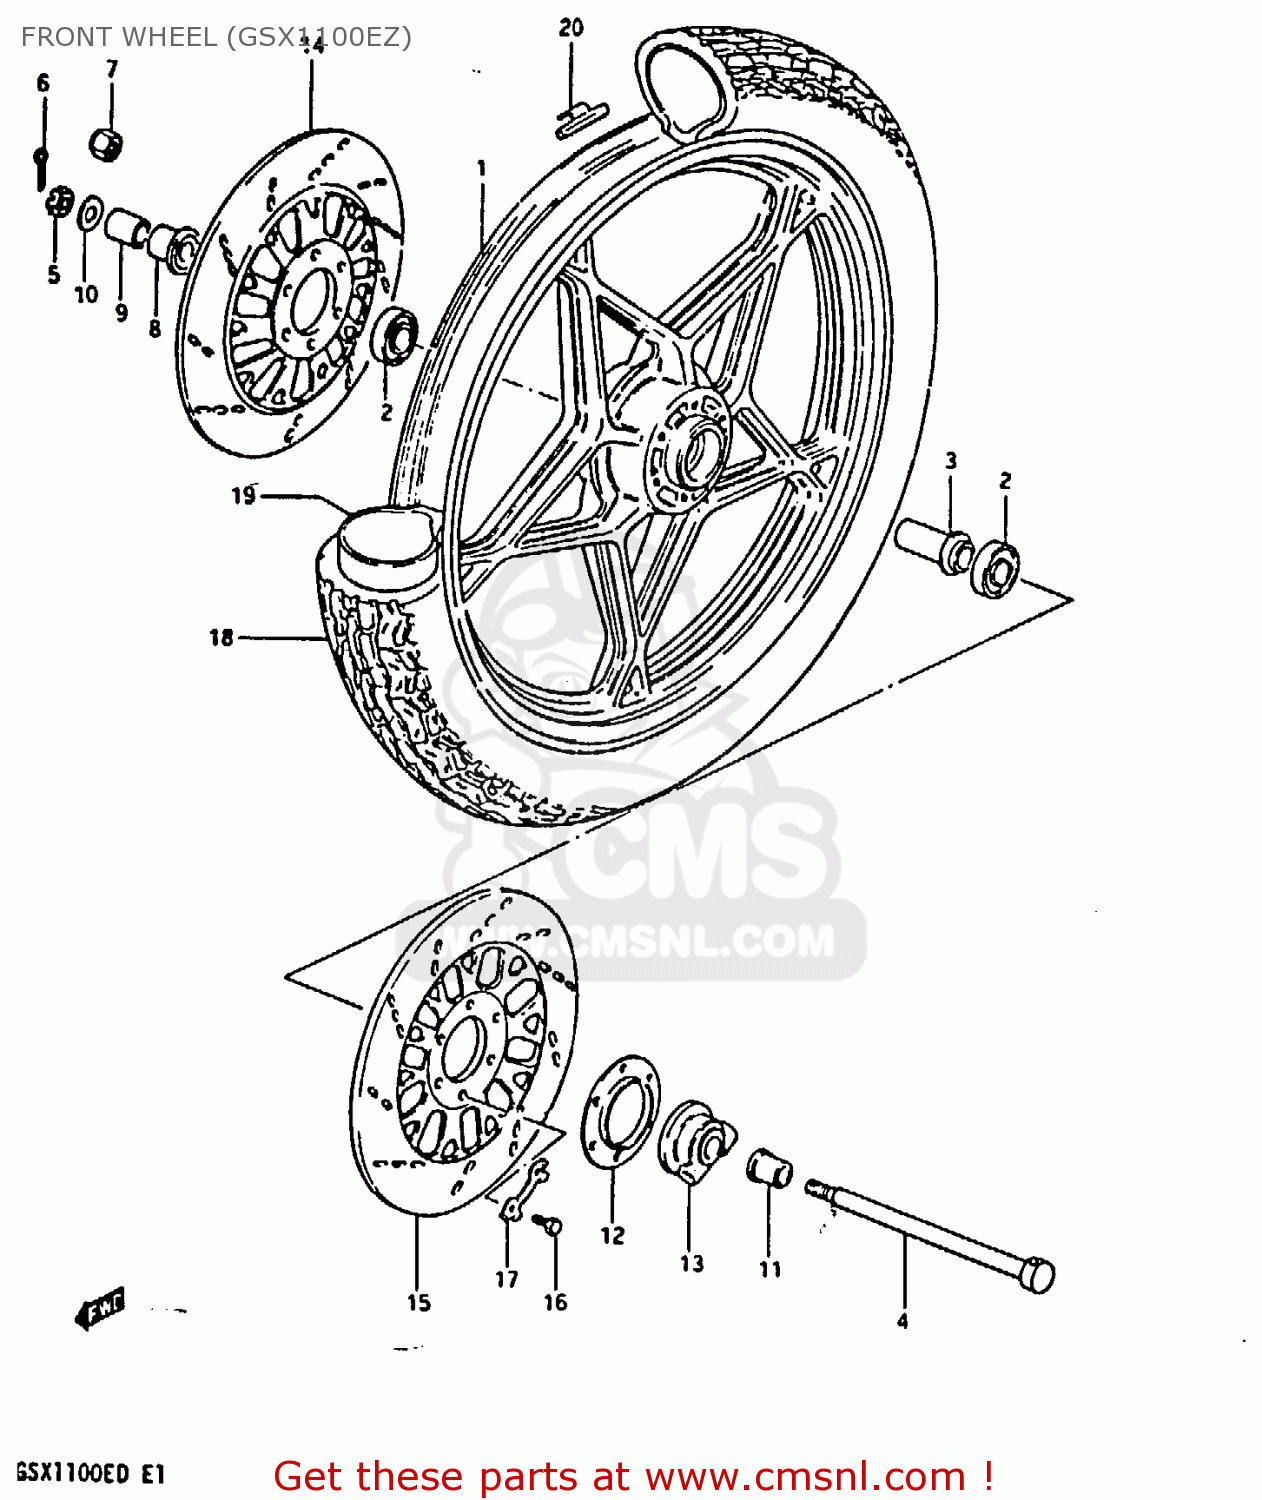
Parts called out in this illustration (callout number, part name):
1	WHEEL, FRONT (19X1.85) (GRAY)
2	BEARING
3	SPACER,FR HUB BEARING
4	AXLE,FR
5	NUT 12MM
6	COTTER PIN
8	SPACER,FR AXLE,R
9	SPACER,FR AXLE,R
10	WASHER
11	SPACER,FR AXLE,L
12	DUST SEAL,SPEEDOMETER GEAR BOX
13	BOX ASSEMBLY,SPEEDOMETER GEAR
14	DISC,FR BRAKE,R
15	DISC,FR BRAKE,L
16	BOLT(8X25)
17	WASHER
18	TIRE,FRONT
19	TUBE,INNER
20	BALANCER,WHEEL
